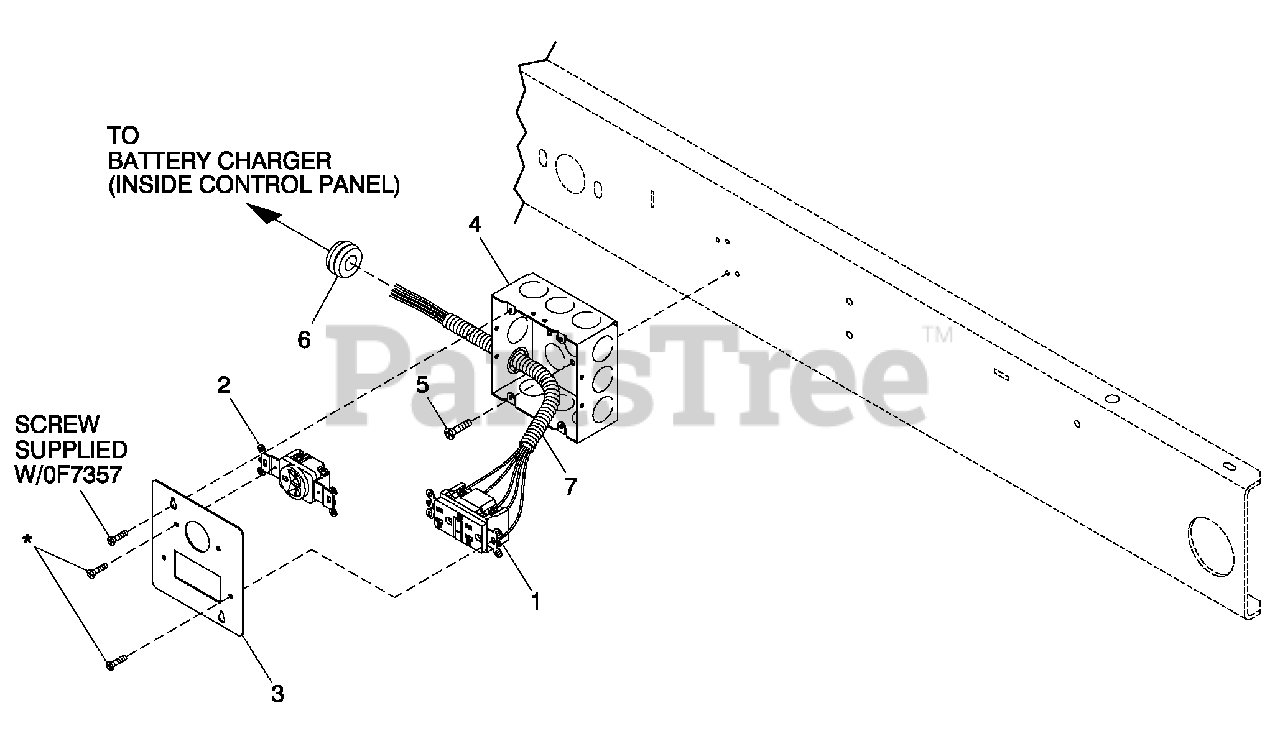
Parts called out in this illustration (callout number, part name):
1	OUTLET 20A GFCI
2	OUTLET 15A 250V NEMA 6-15R IVY
3	BOX SQUARE 4-11/16 W/KNO'S
4	SCREW HHTT #10-24 X 3/8 CZ
5	COVER DUAL RECEPT 120/240
6	GROMMET .87 X .25 X .62
7	HARN ALT CON BOX 1PH QT
